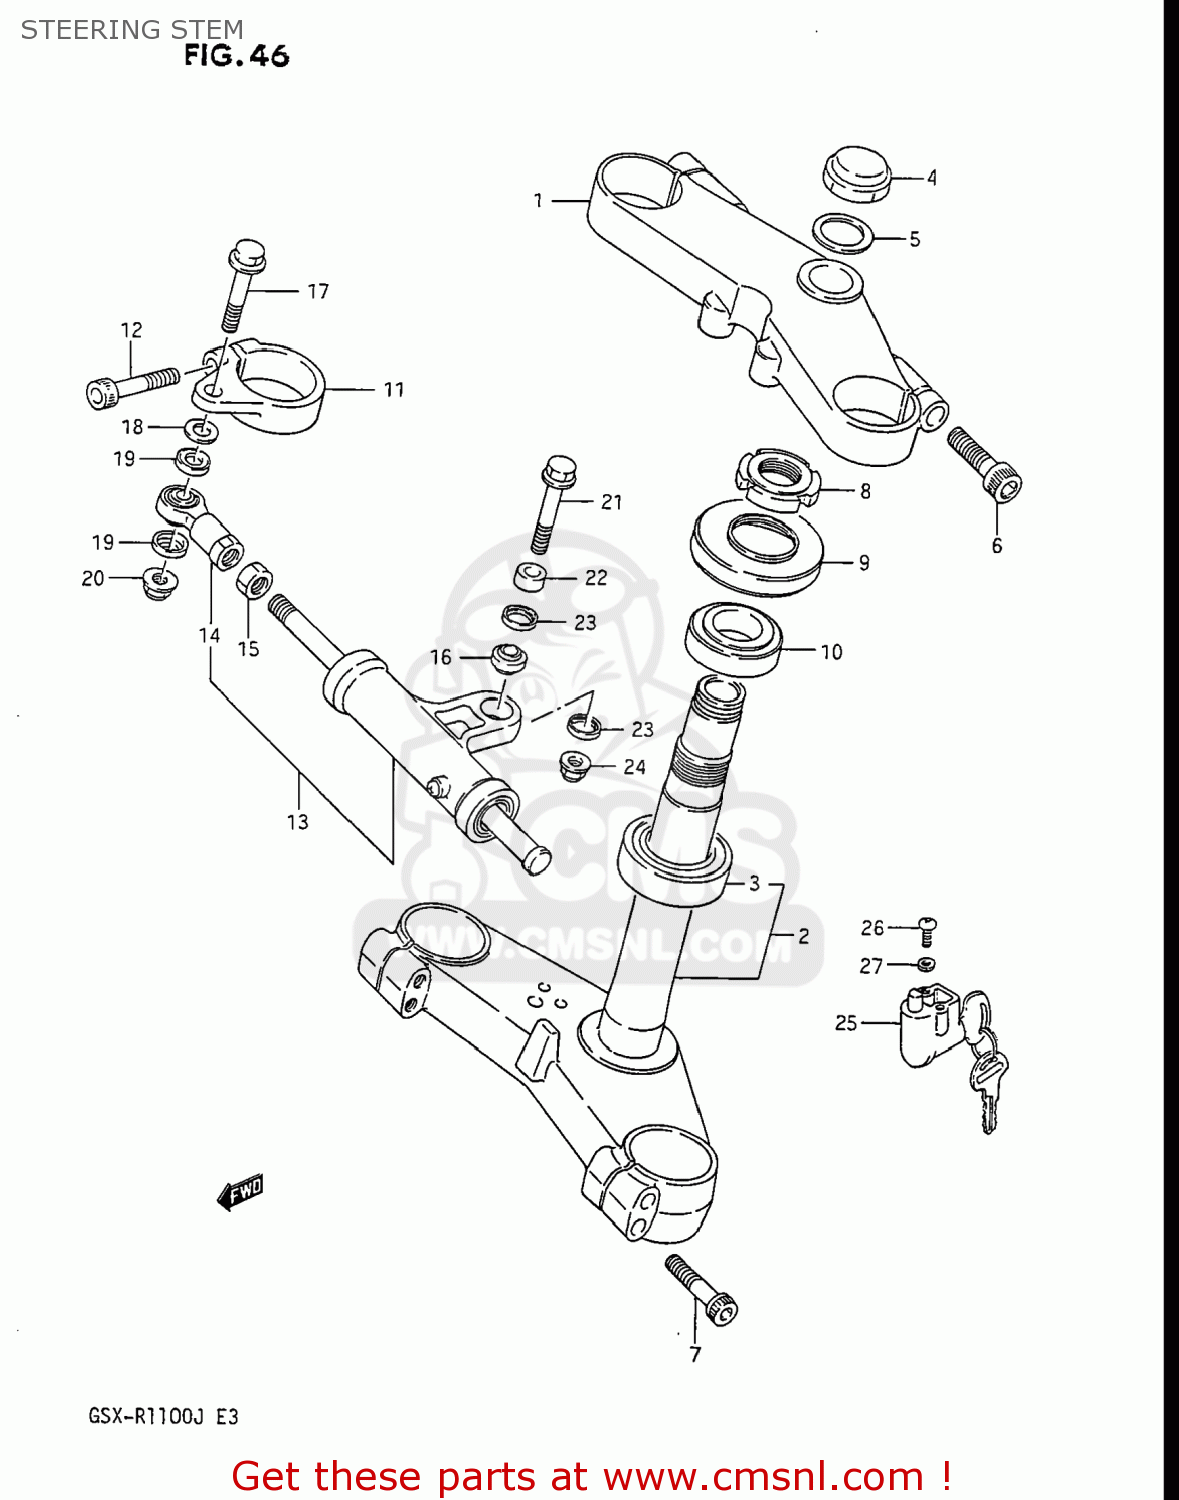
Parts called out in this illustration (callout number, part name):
1	STEM HEAD,STEERING
2	STEM,STEERING
3	BEARING
4	NUT,STEM HEAD
5	WASHER,STEERING STEM
6	BOLT,FORK INNER TUBE FITTING
7	BOLT
8	NUT,STEERING STEM(25X44X10)
9	SEAL OIL
10	TAPER,ROLLER BEARING
11	BRACKET,STEERING DAMPER
12	BOLT
13	DAMPER ASSEMBLY,STEERING
14	BEARING, LOD END
15	NUT
16	BEARING(8X18X11)
17	BOLT(8X33)
18	WASHER
19	20
20	NUT
21	BOLT(8X45)
22	SPACER (8.5X15X10)
23	24
24	NUT
25	LOCK ASSY,STEERING
26	LOCK WASHER
27	SCREW 5X20
